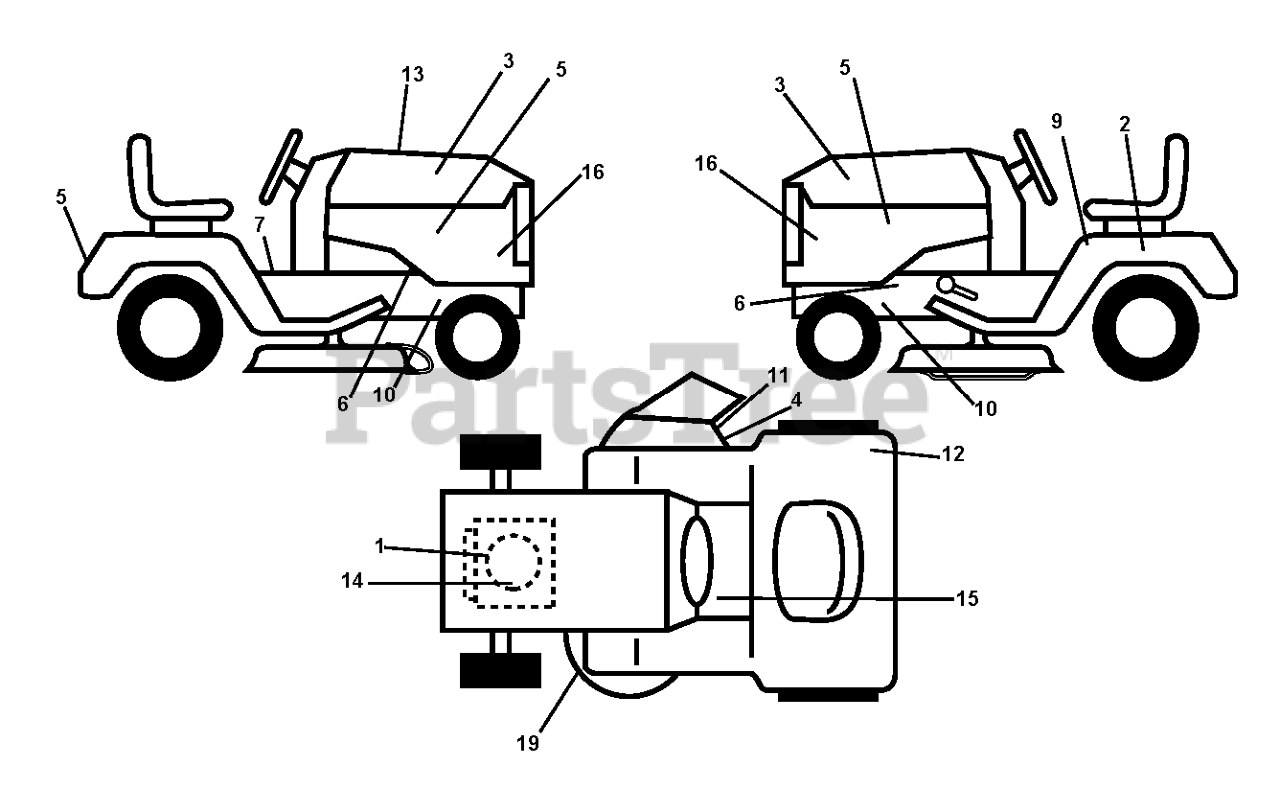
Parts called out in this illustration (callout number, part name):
1	DECAL
2	DECAL BTRY SYMBOLS
4	DECAL, DEFLECT WARNING
5	DECAL.HOOD.LOGO.ORANGE.HUSQVAR
7	DECAL PARK BRAKE
9	LABEL
11	DECAL.INTERNATIONL.CUTFINGER
12	Decal, Fender 100 DB/CE
14	DECAL
15	DECAL
19	DECAL.V-BELT.SCHEMATIC.36/38/9
